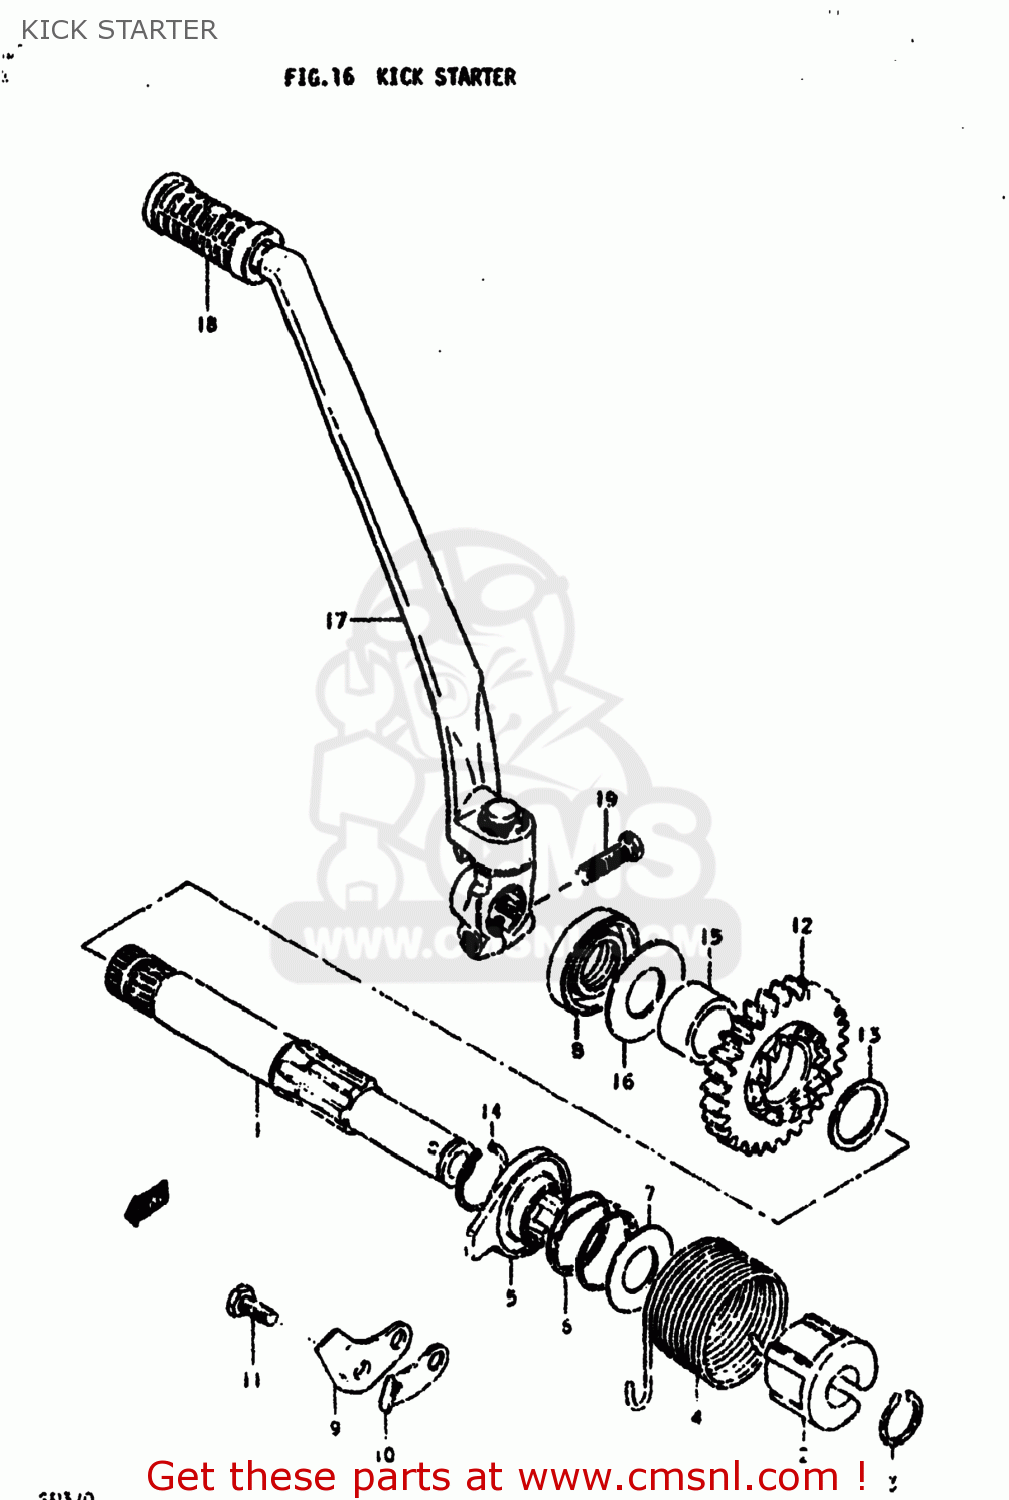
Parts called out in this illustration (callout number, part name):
1	SHAFT,KICK STARTER
2	GUIDE,KICK STARTER SFT SPRING
3	CIRCLIP
4	SPRING
5	STARTER,KICK
6	SPRING
7	PLATE
8	SEAL,OIL(20X37X7)
9	GUIDE,KICK STARTER
10	STOPPER,KICK STARTER
11	BOLT
12	GEAR,KICK STARTER DRIVE(NT:29)
13	WASHER,LOCK
14	CIRCLIP
15	SPACER
16	PLATE, OIL RESERVOR
17	LEVER ASSY,KICK STARTER
18	COVER
19	BOLT(8X25)
